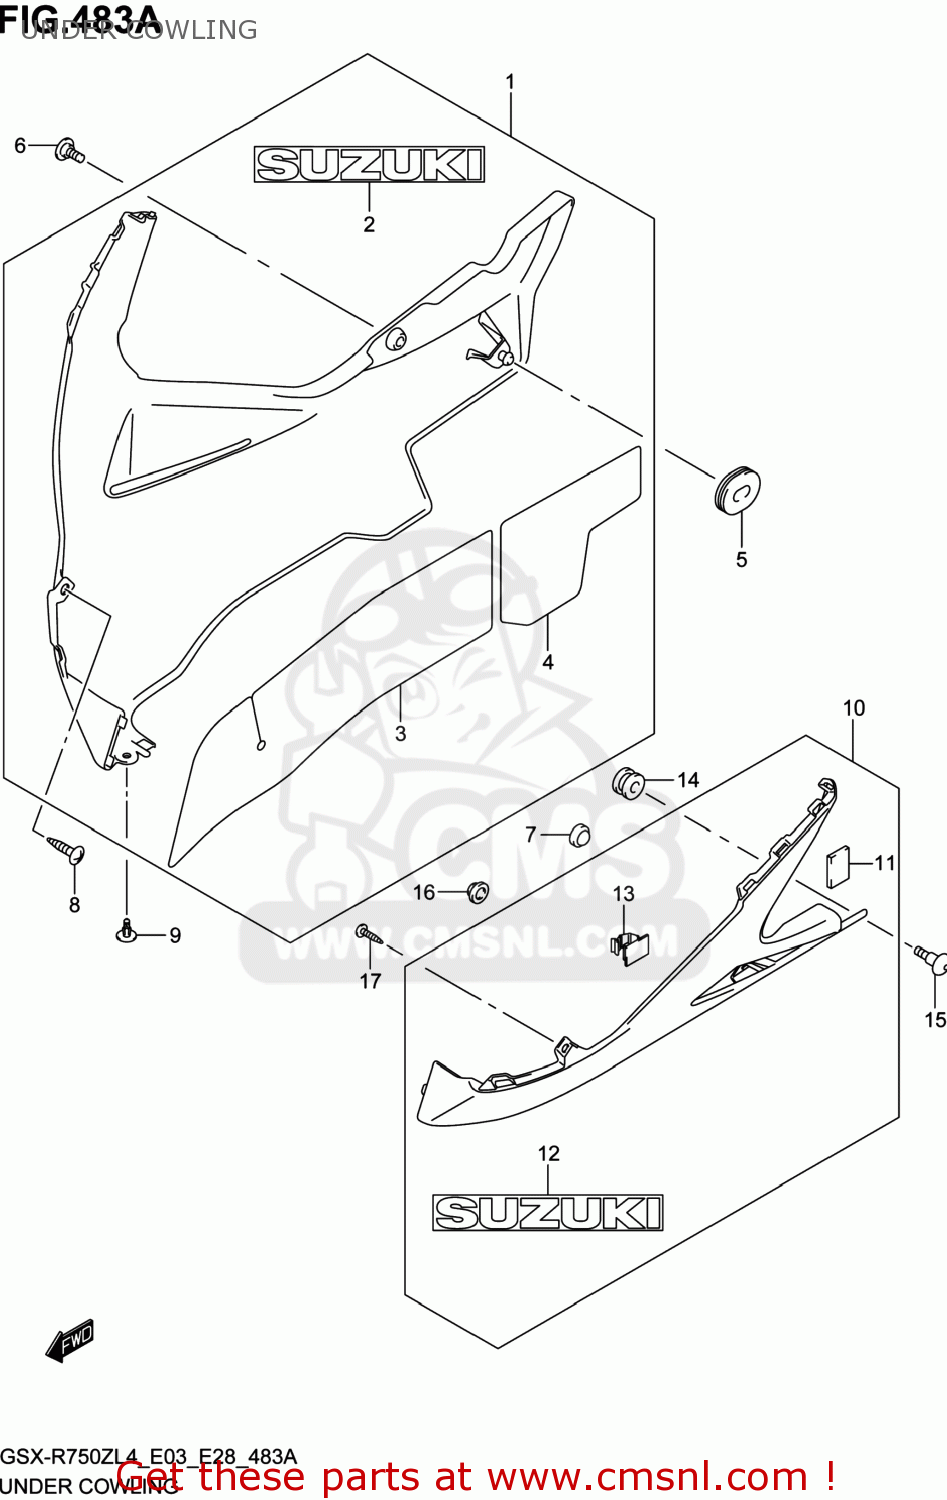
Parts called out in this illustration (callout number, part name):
1	COWLING,UNDER,R(BLACK)
2	EMBLEM,"SUZUKI",R
3	SHIELD,UNDER COWL HEAT,R
4	SHIELD,UNDER COWL HEAT,R
5	CUSHION,UNDER COWLING,R
6	SCREW,UNDER COWL,R
7	CUSHION
8	SCREW
9	CLIP
10	COWLING,UNDER,L(BLACK)
11	CUSHION,BRACKET NO.1
12	EMBLEM,"SUZUKI",R
13	CLAMP
14	CUSHION
15	BOLT(6X20)
16	CUSHION
17	SCREW
